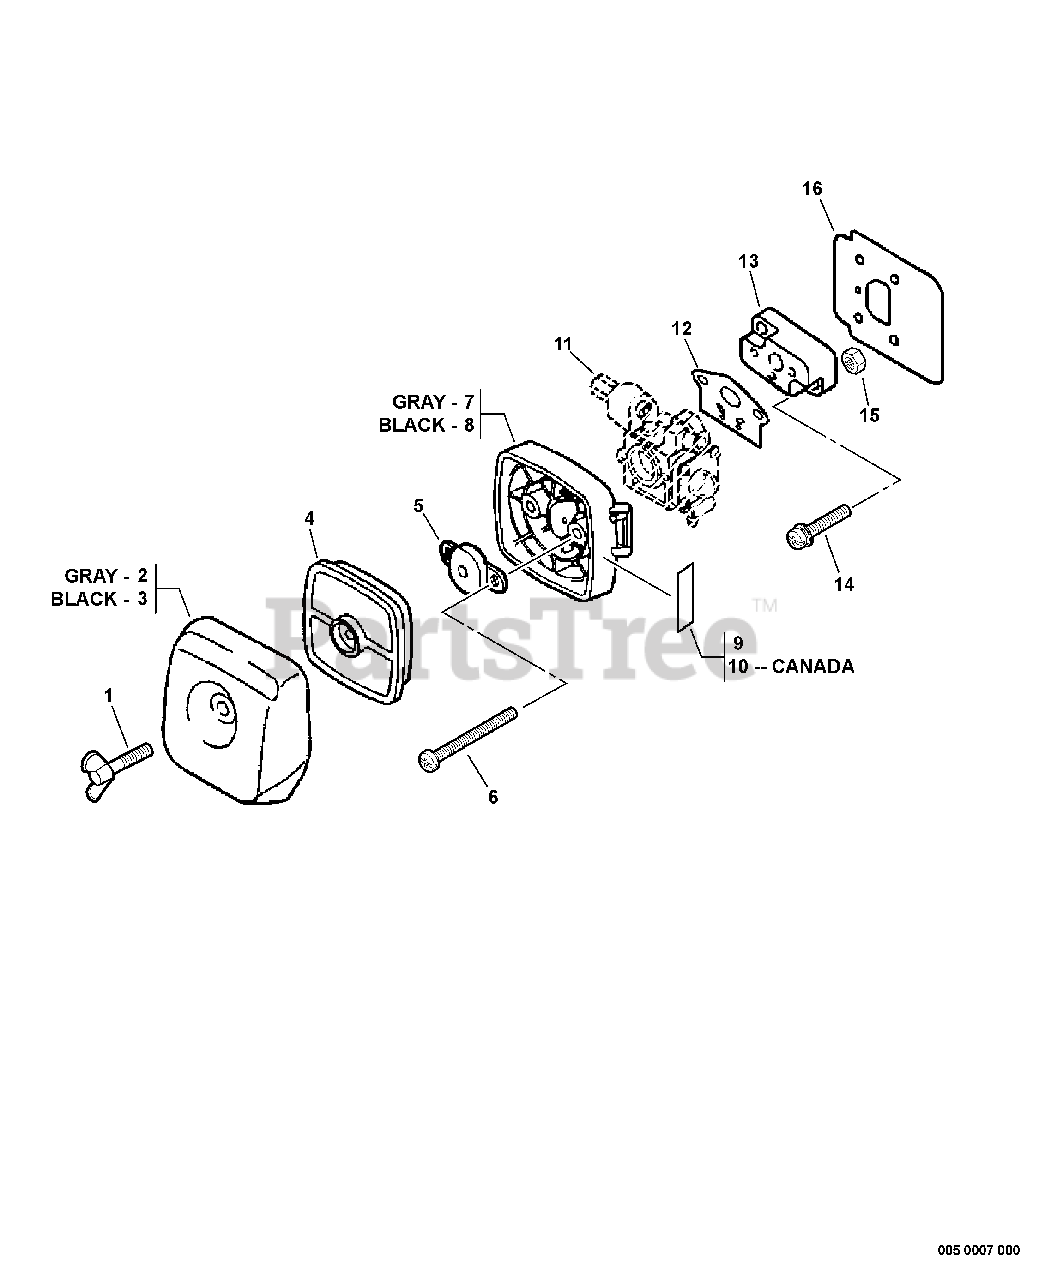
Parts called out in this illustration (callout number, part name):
1	BOLT, WING 5×20
2	COVER, AIR FILTER - GRAY
3	COVER, AIR FILTER - BLACK
4	FILTER, AIR - SINGLE LAYER
5	PLATE, PREVENT
6	SCREW 5×65
7	CASE, AIR FILTER - GRAY
8	CASE, AIR FILTER - BLACK
9	LABEL, CHOKE
10	LABEL, CHOKE
11	CARBURETOR
12	GASKET, CARBURETOR
13	INSULATOR, INTAKE
14	SCREW 5×20
15	NUT M5
16	HEAT SHIELD, INTAKE
